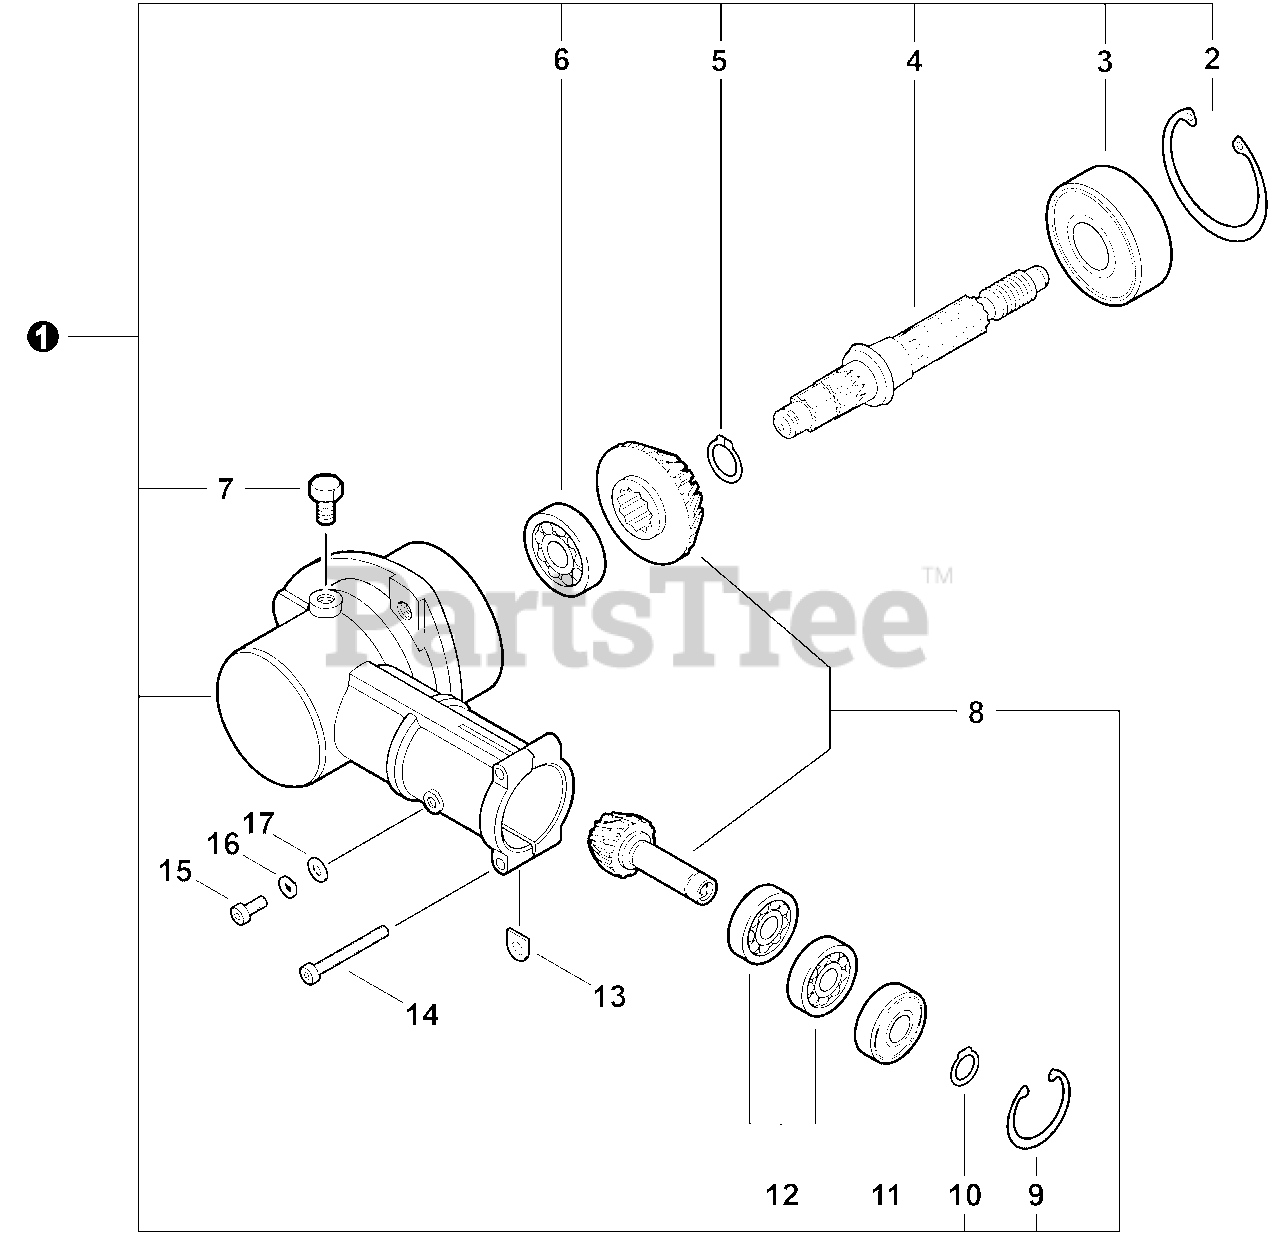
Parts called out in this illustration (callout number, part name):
1	GEAR CASE ASSY
2	RING, SNAP Ø42
3	BEARING, BALL 6302
4	SHAFT, GEAR
5	RING, SNAP Ø12
6	BEARING, BALL 629
7	BOLT M8×8
8	GEAR SET
9	RING, SNAP Ø22
10	RING, SNAP Ø10
11	BEARING, BALL 6900Z
12	BEARING, BALL 6900
14	BOLT, TORX 5×25
15	BOLT, TORX 5×12
16	WASHER, SPRING 5
17	WASHER, FLAT 5.5×10×0.8
